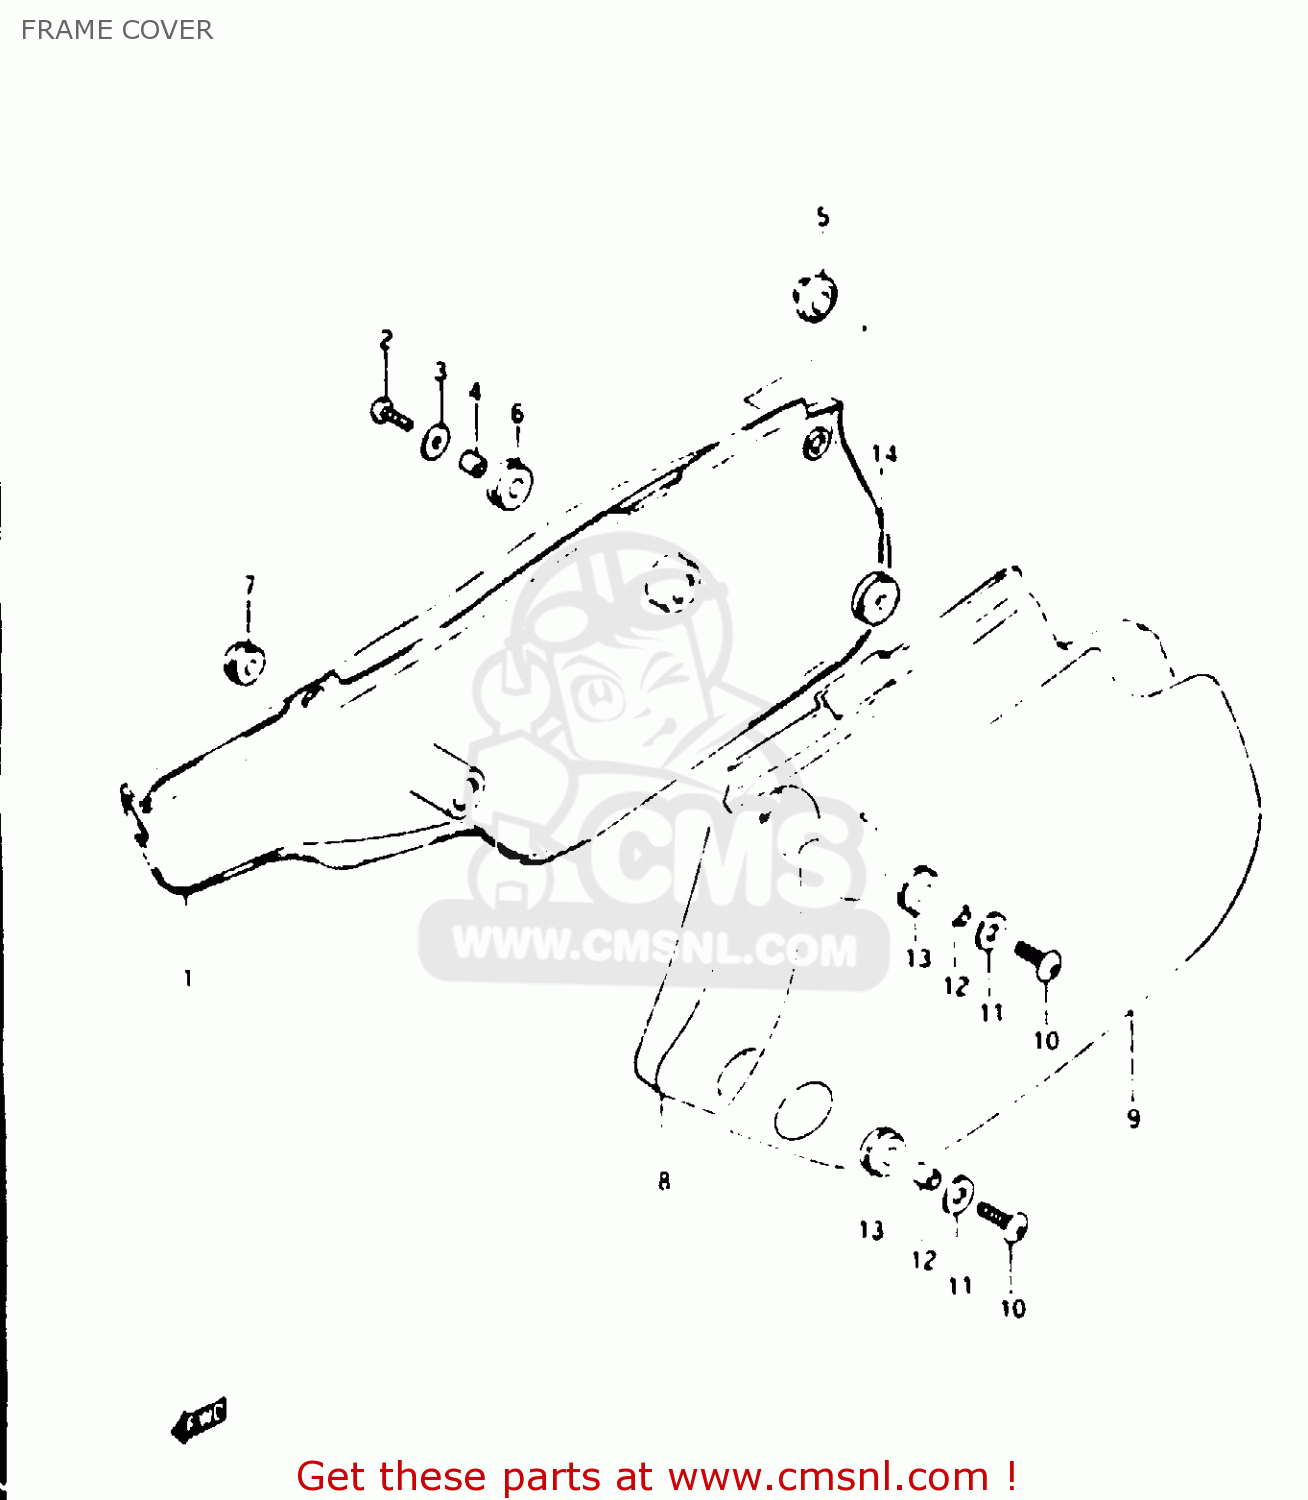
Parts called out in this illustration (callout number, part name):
1	COVER, FRAME RH
2	SCREW, CENTER
3	WASHER (6.5X18X1.6)
4	SPACER (6.3X9.1X6.7)
5	CUSHION
6	CUSHION
7	CUSHION,FRAME COVER,R UPR
8	COVER, FRAME LH (RED)
9	EMBLEM, LH (BLUE)
10	SCREW, CENTER
11	WASHER (6.5X18X1.6)
12	SPACER (6.3X9.1X6.7)
13	CUSHION
14	CUSHION
